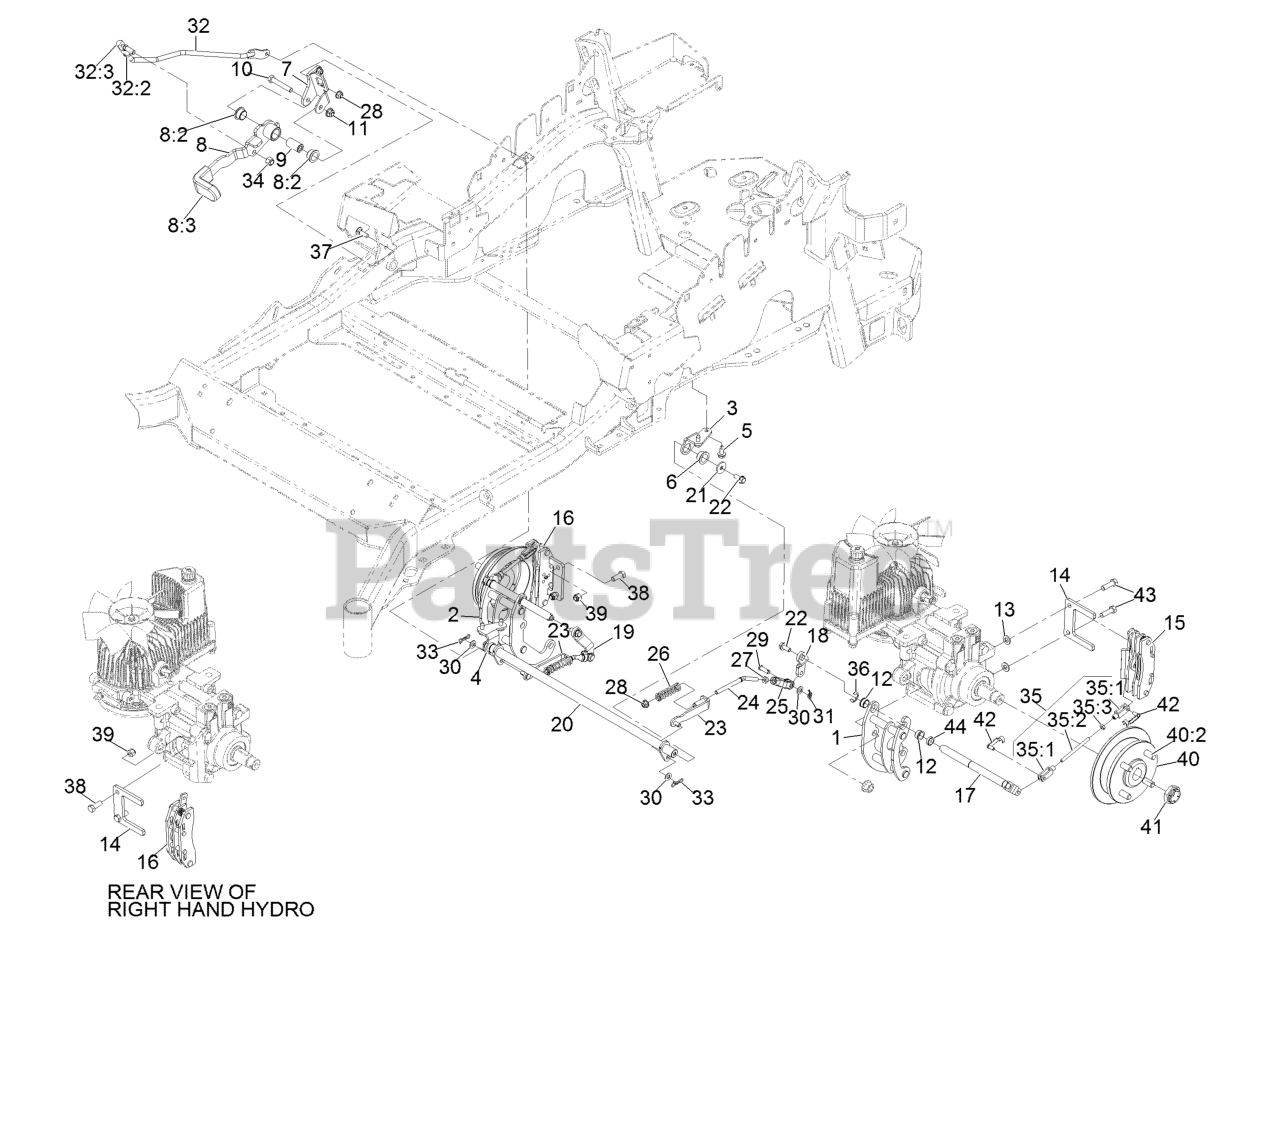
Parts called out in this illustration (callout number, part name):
1	Mount-Bellcrank, LH
2	Mount-Bellcrank, RH
3	Mount-Pivot, LH
4	Mount-Pivot, RH
5	Screw-HWH 5/16-18 X 3/4 Tf
6	Bushing-Flanged
7	Bracket-Mount
8	Brake Lever ASM W/ Grip
8:2	Bushing-Flanged
8:3	Grip-Lever
9	Handle-Pivot, Brake
10	Screw-HH 3/8-16 X 2 1/4
11	Nut-Nyloc 3/8-16 Flg
12	Bushing
13	Washer-3/8 SAE
14	Plate-Mount, Brake
15	Caliper-Brake
16	Caliper-Brake,RH
17	Bellcrank
18	Arm-Inner, LH
19	Arm-Inner, RH
20	Shaft-Cross
21	Washer-Flat
23	Bracket-L
24	Linkage-Mid
25	Yoke-Offset
26	Spring-Compression
27	Nut-Jam 5/16-24
28	Nut-Nyloc 5/16-18 Flg
29	Pin-Clevis 5/16 X 1 49/64
30	Washer-5/16 SAE
31	Pin-Cotter, Locking
32	Front Linkage ASM
32:2	End-Tie Rod, RH
32:3	Nut-Jam 3/8-24
33	Pin-Cotter, Locking
34	Nut-Nyloc 3/8-24
35	Rear Linkage ASM
35:1	Yoke
35:2	Linkage, Rear
35:3	Nut-Jam 1/4-28
37	Bolt-Carriage 5/16-18 X 1
38	Screw-HH 3/8-16 X 1
39	Nut-Nyloc 3/8-16
40	Wheel Hub ASM
40:2	Stud-Wheel
41	Locknut
42	Pin-Clevis, Spring
43	Screw-HH 3/8-16 X 1 1/4 Patch Lock
